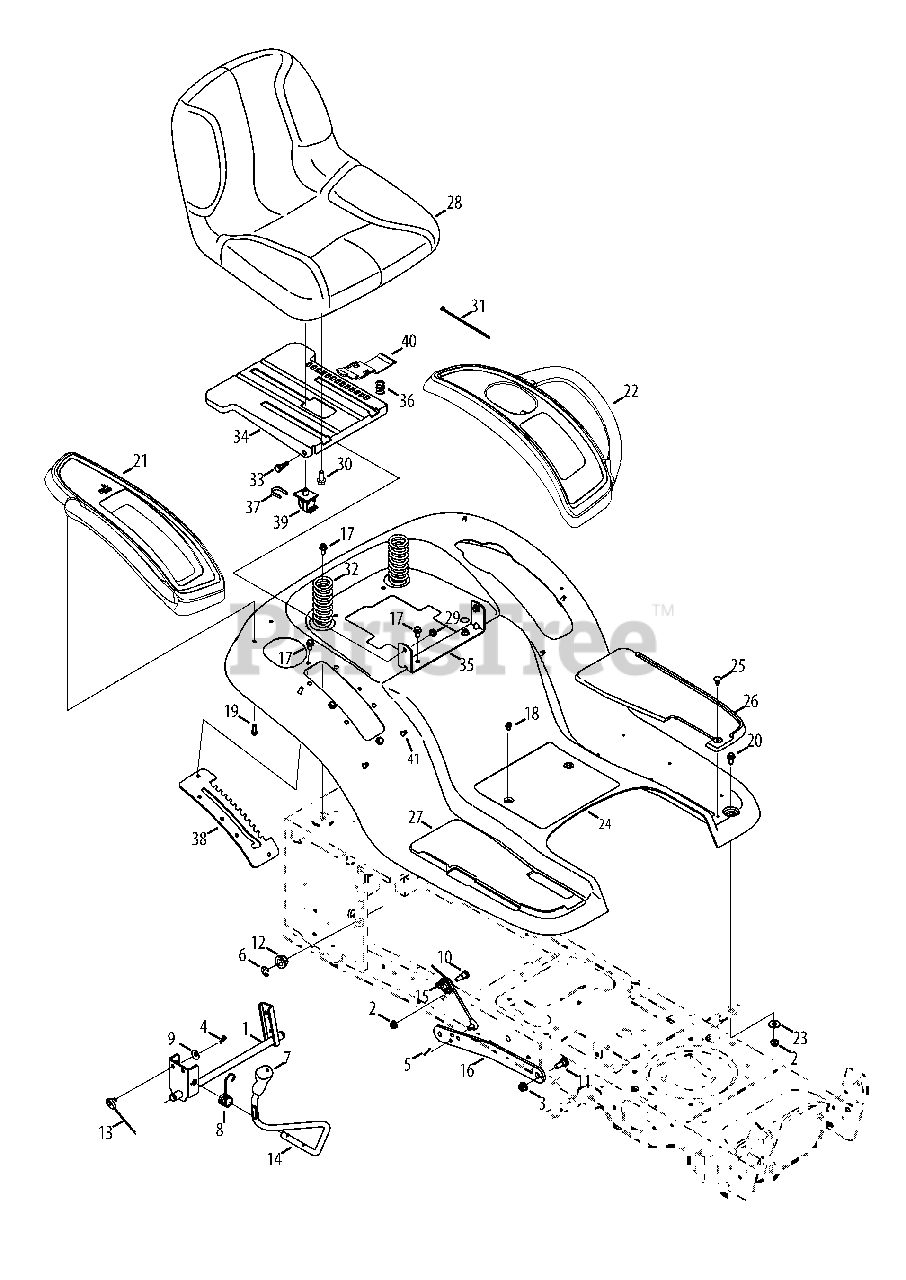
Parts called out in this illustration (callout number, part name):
1	Lift Shaft Assembly
2	Flangelock Nut, 5/16-18
3	Flangelock Nut, 3/8-16
4	Cotter Pin, .072 DIA. x 1.13 LG
5	Bow-Tie Cotter Pin
6	E-Ring, .625 DIA. SHAFT
7	H&le Grip
8	Torsion Spring
9	Spring Washer, .401 x .870 x .063
10	Shoulder Screw, .437 x .470:5/16-18
11	Shoulder Bolt, .500 x .270:3/8-16
12	Hex Flange Bearing
13	Lift Cable, 16.64 LG
15	Pulley Roller Cable
17	Taptite Screw, Lock Washer, 5/16-18
18	Taptite Screw, Lock Washer, 1/4-20
19	Hi-Lo Screw, Lock Washer, 1/4-15
20	Taptite Screw, 5/16-18:.750
21	Fender Cover RH
22	LH Fender Cover
23	Flat Washer, .344 x 1.00 x .063 HDN
25	Ratchet Clip
26	LH Foot Pad
27	RH Foot Pad
28	Seat
29	Flangelock Nut, 5/16-18
30	Hex Head Flange, 3/8-16:.875
31	Cable Tie, 3/16 x .05 x 7.4
32	Compression Spring, 1.50 x 3.90 x .200
33	Shoulder Screw, .437 x .268:5/16-18
34	Seat Mounting Bracket
35	Seat Pivot Bracket
36	Comp. Spring, .68 x 1.065 x .055
37	Switch Retainer Clip
39	Seat Switch
40	Seat Adjustment Lever
41	Screw, 1/4-15 x 0.50
